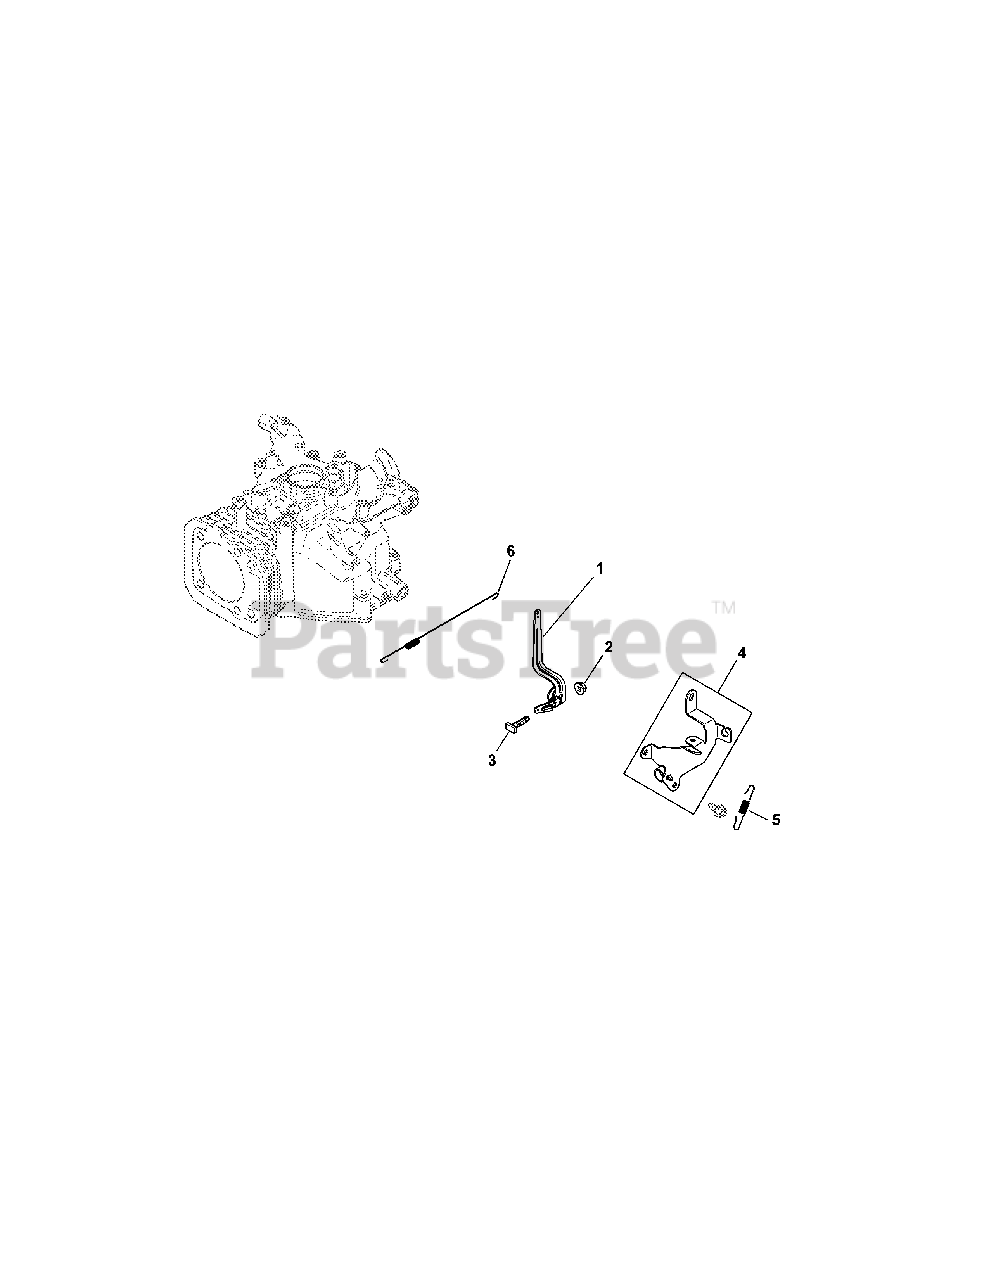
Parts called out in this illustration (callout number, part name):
1	Governor Lever
2	Nut, Hex Flange, M6
3	Screw, Rectangle Head, M6
4	Control Bracket
5	Governor Spring
6	Linkage Spring
